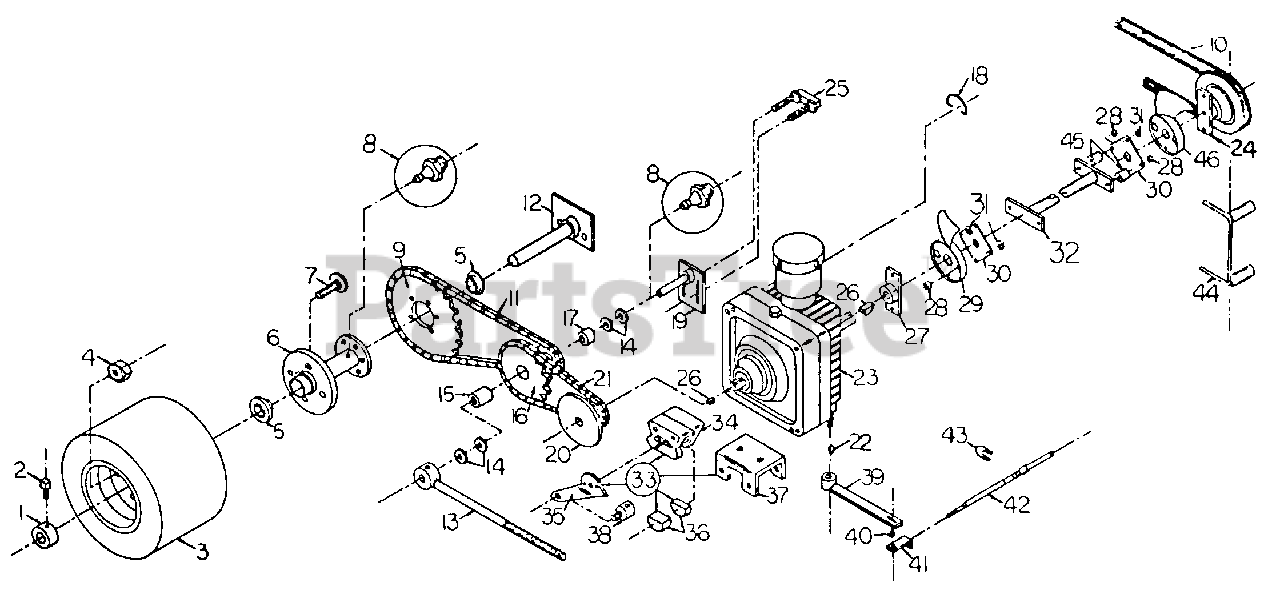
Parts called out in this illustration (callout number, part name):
1	See Collar, l"
2	Squarehead Setscrew, 5/16-18 x 1/2"
3	Drive Wheel Ass'y., 16 x 7.50-8
4	Lug Nut, 1/2-20
5	Drive Wheel Bearing
6	Drive Wheel Hub
7	Lug Bolt, 1/2-20 x 1 1/4"
8	Self-tapping Zerk, 1/4-28
9	Flnal Drive Sprocket, 40A 54
10	Transmission Belt
11	Final Drive Chain
12	Drive Wheel Axle
13	Support Collar
14	Machine Washer, 3/4", 10 GA
15	Idler Sprocket Bearing, 1/2"
16	Idler Sprocket
17	Idler Sprocket Bearing, 3/4"
18	Transmission Dump Valve Clip
19	Idler Sprocket Shaft
20	Transmission Sprocket w/Brake Disc
21	Primary Drive Chaln
22	Woodruff Key, 1/8" x 3/8"
23	Trangmission, LH
24	Pulley w/Drive Plate
26	Woodruff Key, 1/8" x 1/2"
27	Hub w/Drive Plate
30	Drive Plate
31	Washer, 1/4", 10 GA
33	Brake Assembly, LH
34	Brake Caliper
35	Caliper Lever, LH
36	Brake Pad
37	Caliper Bracket
38	Caliper Rod Collar
39	Transmission Arm, LH
40	Cable End Bushing
41	Steering Cable End
42	Steering Cable
43	Steering Cable Clamp
44	Transmission Belt Retainer
